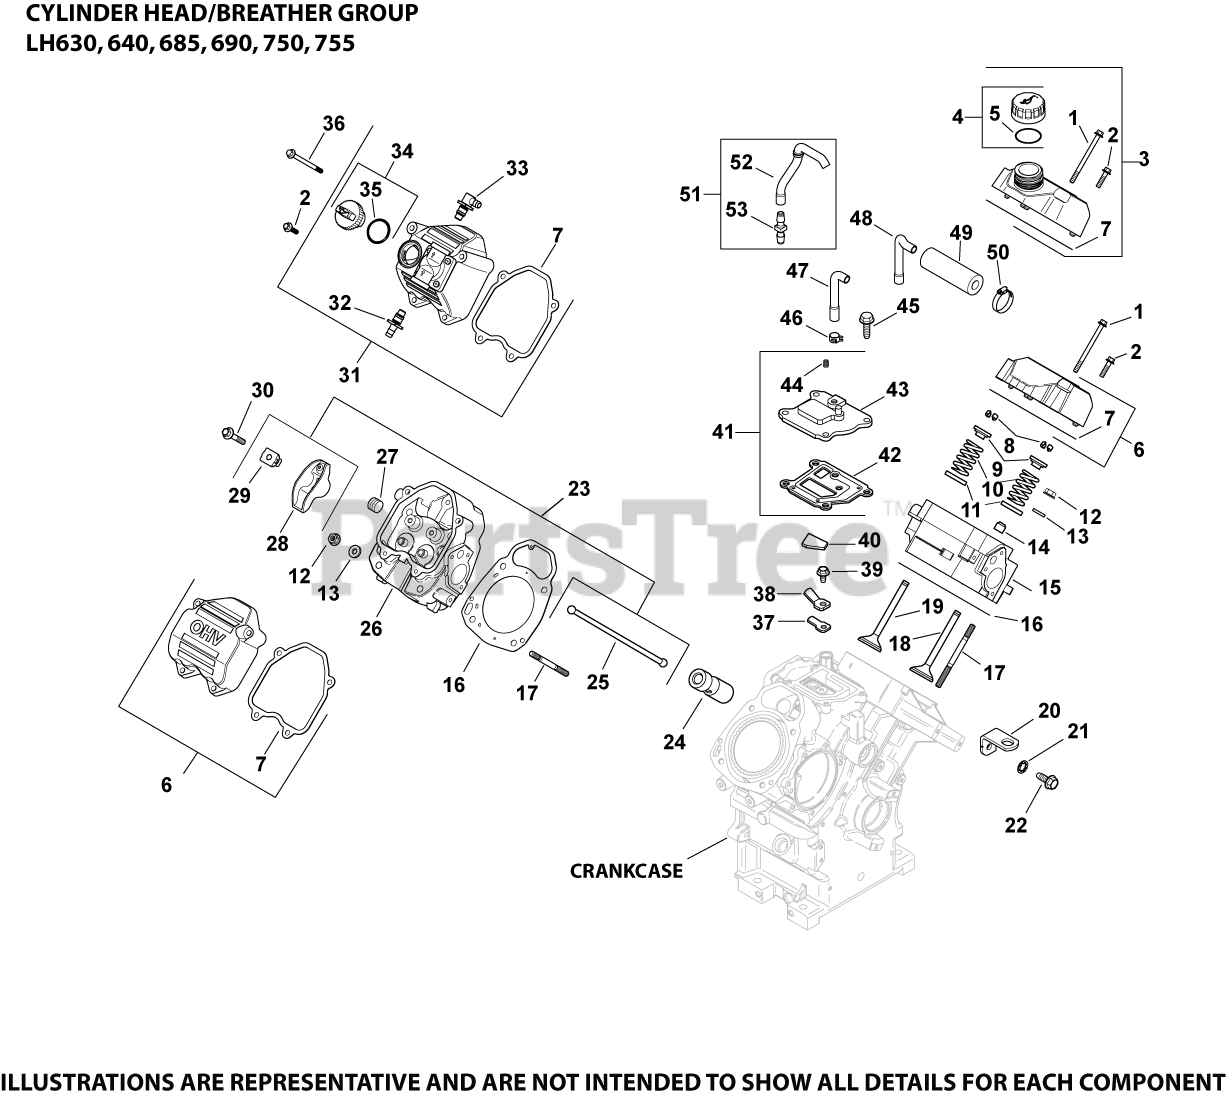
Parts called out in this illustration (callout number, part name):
1	SCREW, FLG M6X1.0X80
2	SCREW, FLG M6X1.0X25
6	KIT, ROCKER COVER
7	GASKET, VALVE COVER
8	KIT, RETAINER
9	CAP, VALVE SPRING
10	SPRING, VALVE
11	RETAINER, SPRING
12	NUT, FLG M8X1.25
13	WASHER, FLAT 5/16"
14	SEAL, VALVE STEM - (#2503214S)
15	KIT,CYLINDER HEAD #1
16	KIT, CYLINDER HEAD GASKET
18	VALVE, INTAKE (STD)
18	VALVE, INTAKE (.25)
19	VALVE, EXHAUST (STD) - USE 32 016 01-S
19	VALVE, EXHAUST (.25)
23	KIT, VALVE TRAIN
24	LIFTER, VALVE HYDRAULIC - (#2535111S)
25	ROD, PUSH
26	KIT,CYLINDER HEAD #2
27	PLUG, PIPE
28	ARM, ROCKER
29	PIVOT, ROCKER ARM
30	SCREW, FLG M6X1.0X34
31	KIT, FUEL PUMP/ROCKER COVER
32	KIT, STRAIGHT FITTING
33	KIT, 90 DEG. FITTING
34	CAP ASSY, OIL FILL (YELLOW)
35	O-RING-USE 24 153 32-S
36	SCREW, FLG M6X1.0X55
37	REED, BREATHER
38	RETAINER, REED
39	SCREW, FLG THD FRM M5X.8X10
40	FILTER, BREATHER
41	KIT, BREATHER ASSEMBLY
42	GASKET, BREATHER
43	COVER, BREATHER -USE 24 033 01-S
44	PLUG, CTSK PIPE 1/8"
45	SCREW,FLG THD FRM M6X1.0X20-(#25086396S)
46	CLAMP, BAND SPRING HOSE-(#2523737S)
47	HOSE, BREATHER
50	CLAMP, HOSE (KM)-USE 25 237 31-S
